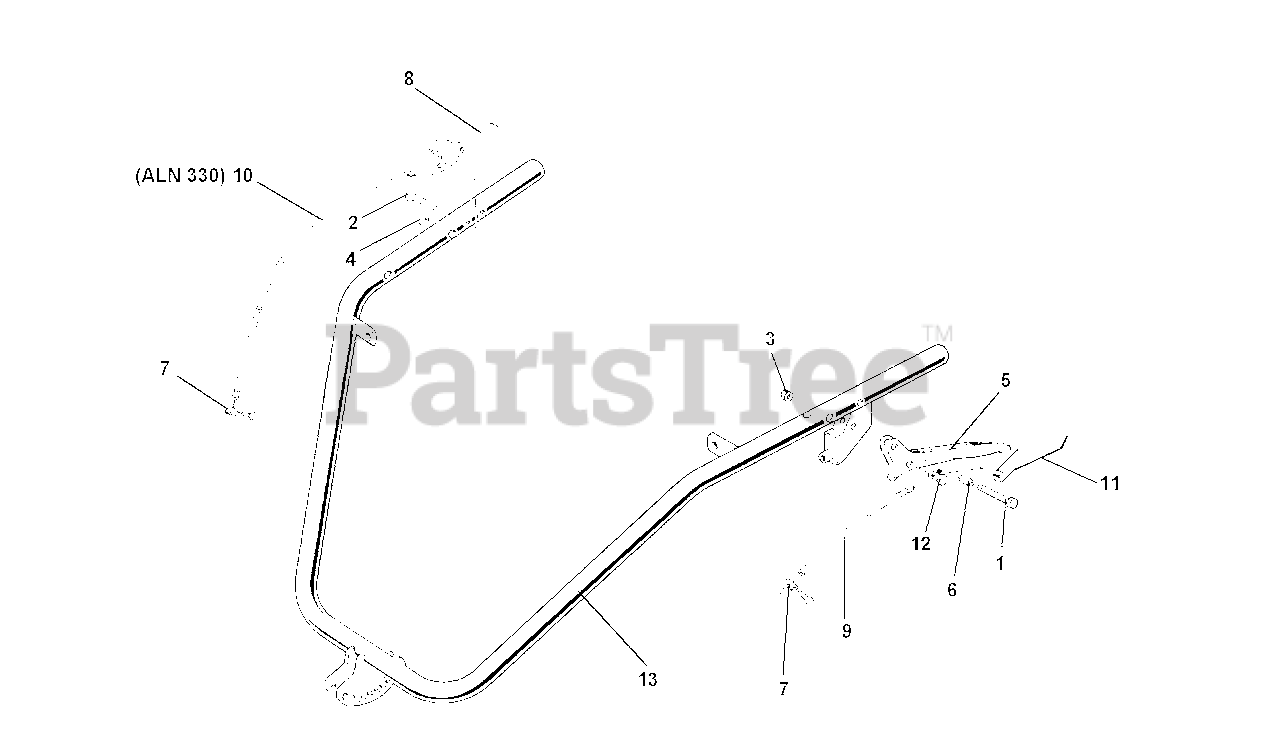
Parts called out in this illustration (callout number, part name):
1	SCREW M6 X 25
2	SCREW M6 X 40
3	NUT, SELF LOCKING M6
4	WASHER, LOCK 8.4
6	LEVER SPACER
7	CLAMP, CABLE
8	LEVER, ACCELERATOR
9	CABLE & SHEATH, CLUTCH
10	WIRE, SHEATH 1850 GAS
11	LEVER SPRING
